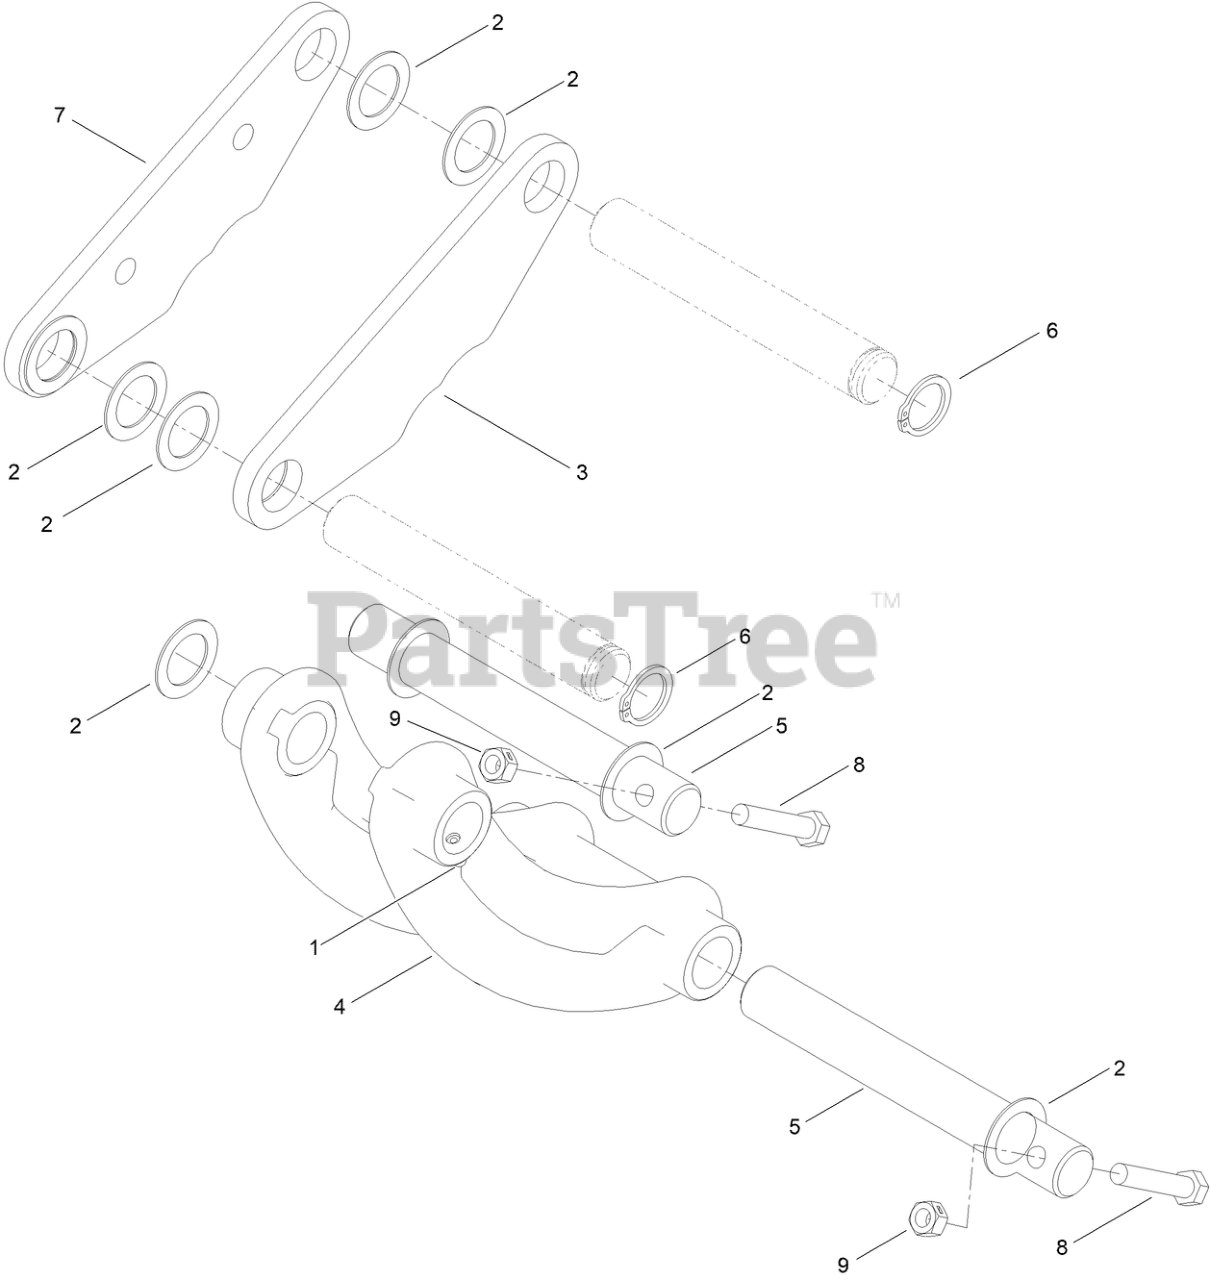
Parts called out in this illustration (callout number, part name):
1	FITTING-GREASE
2	WASHER
3	BRACKET-CYLINDER
4	BRACKET-BUCKET
5	PIN-BUCKET
6	LOCK CLIP-PIN
7	PIVOT-WELDMENT
8	SCREW-HH
9	NUT-LOCK
